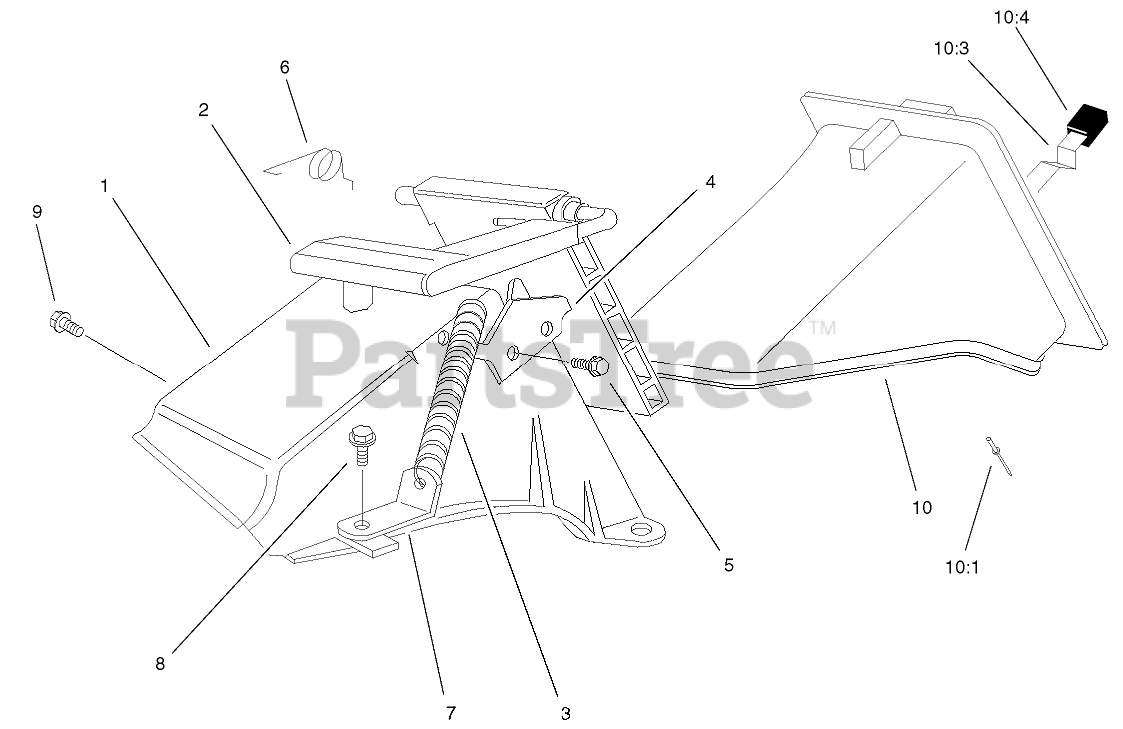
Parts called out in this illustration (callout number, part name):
1	TUNNEL-DISCHARGE
2	DISCHARGE DOOR ASM
3	SPRING-DOOR
4	LATCH-PLATE
5	SCREW-PLASTITE
6	RETAINER-DOOR
7	BRACKET-SPRING
8	SCREW-HWH
9	SCREW AND WASHER ASM
10	DISCHARGE PLUG ASM
10:1	RIVET-HEAD, FLAT
10:3	LATCH-PLUG, DISCHARGE
10:4	GRIP-LATCH
